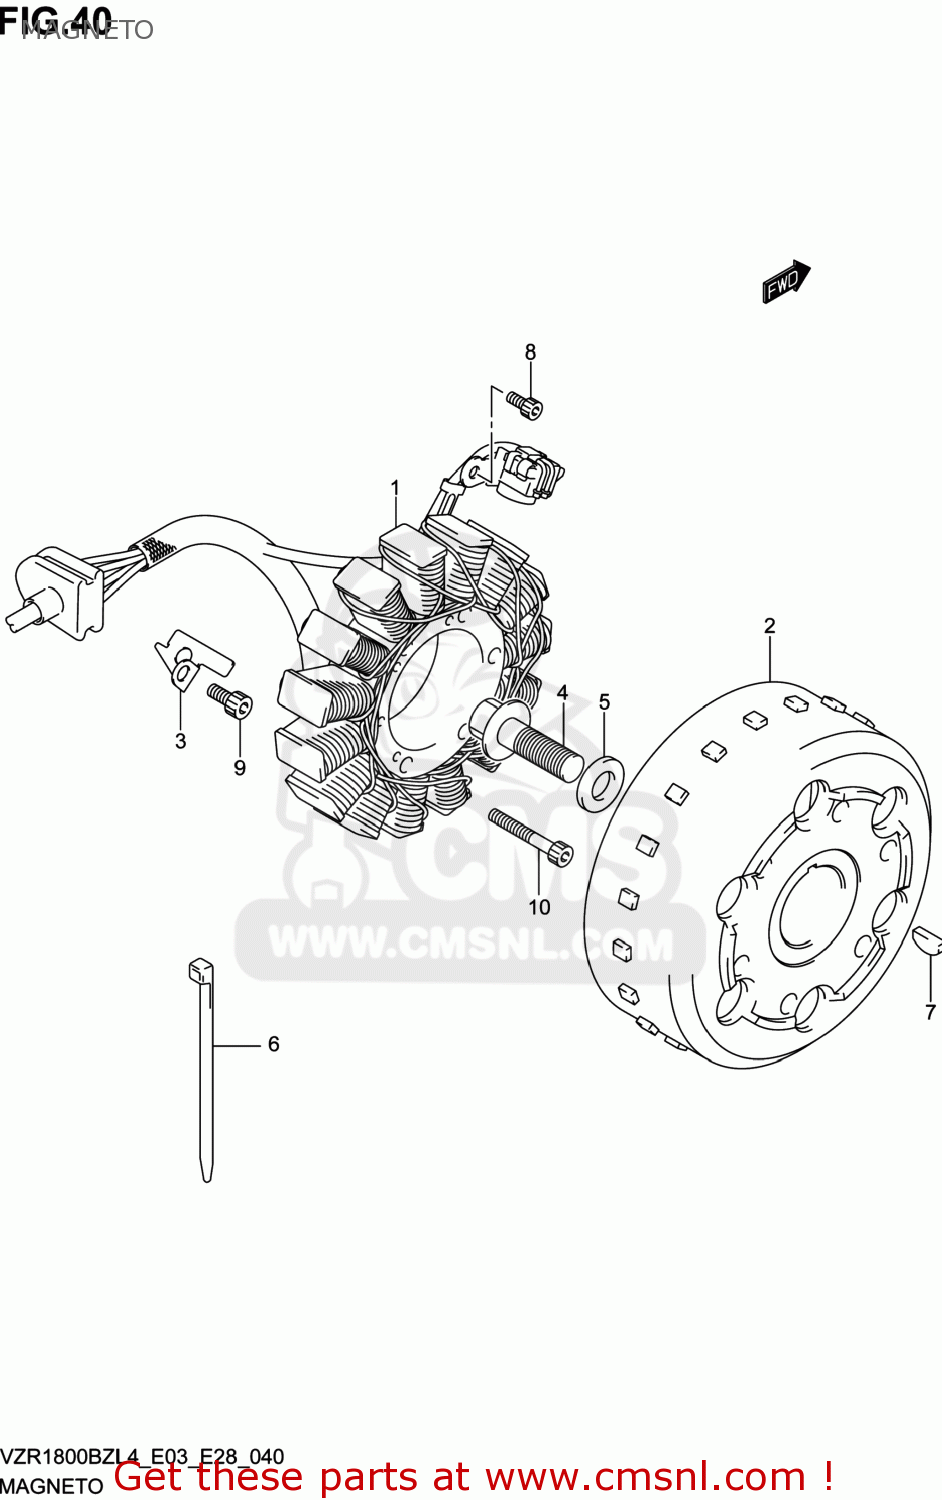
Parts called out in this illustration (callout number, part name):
1	STARTER ASSY
2	ROTOR ASSY
3	CLAMP,MAGNETO LEAD
4	BOLT(14X43)
5	WASHER(14X29X4)
6	CLAMP(L:145)
7	KEY
8	BOLT
9	BOLT
10	BOLT(6X30)
